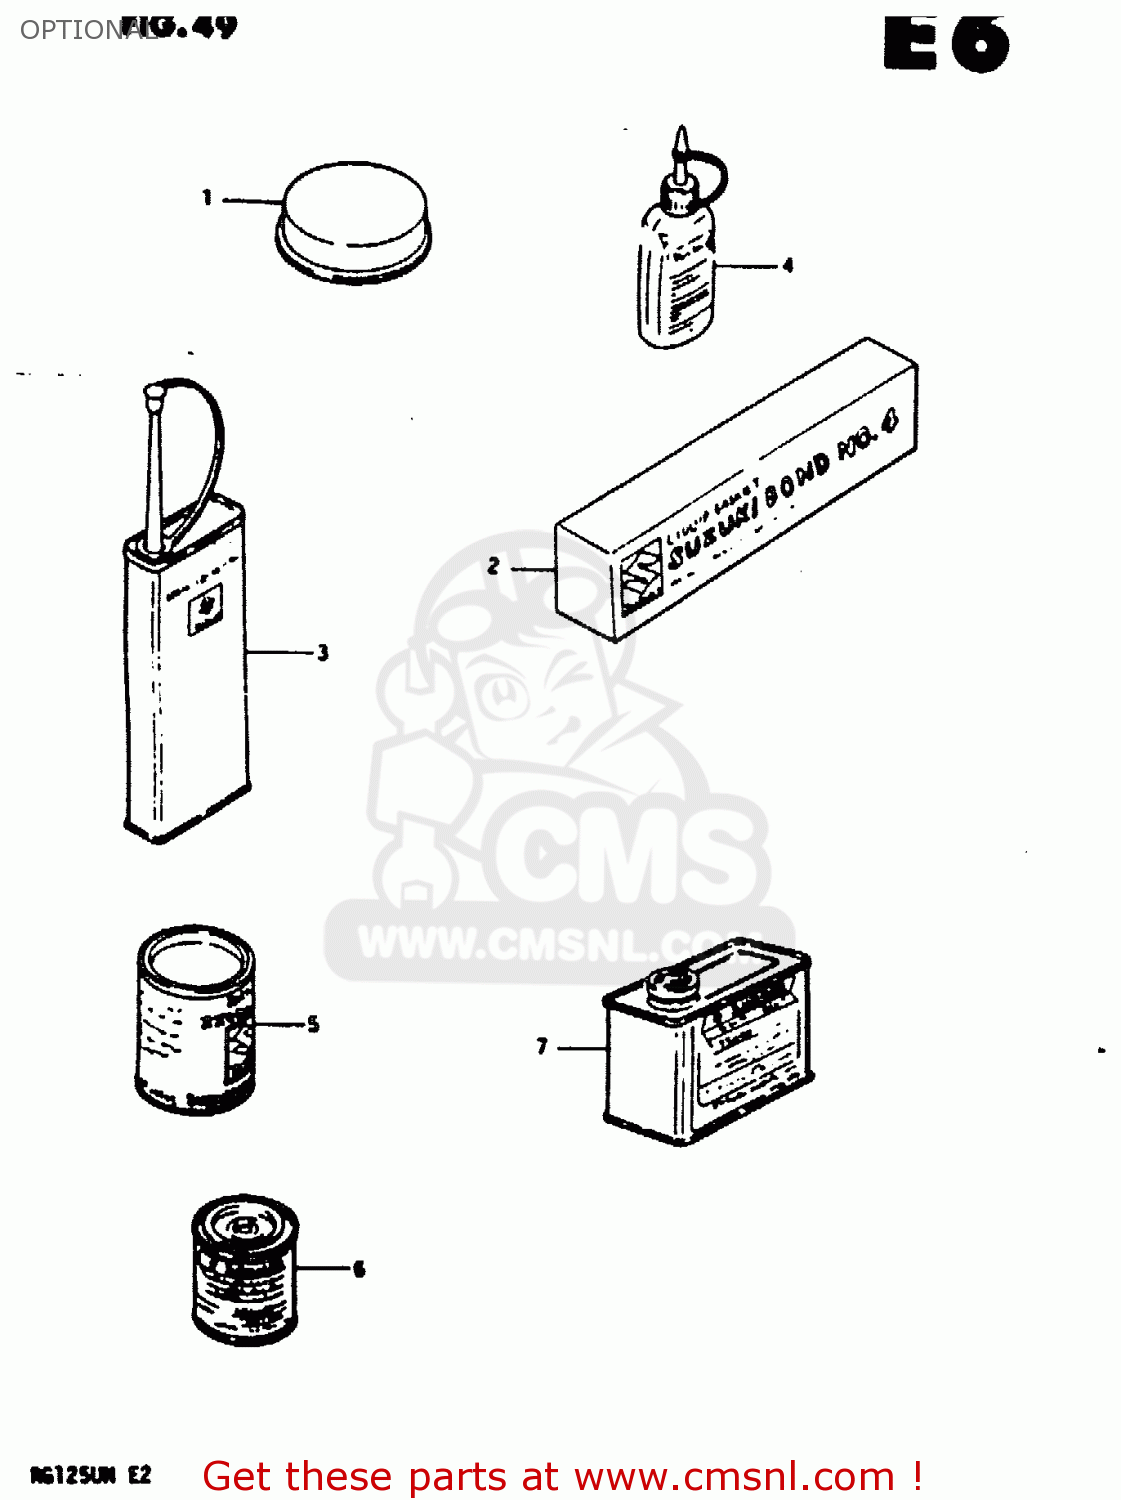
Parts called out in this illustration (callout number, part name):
1	GREASE,PBC FOR BRK PAD 20G
2	BOND 1104
3	THREAD LOCK NO.1401 CLEAR 200G
4	THREAD LOCK NO
5	GREASE(C)EP2 LITHIUM 150G
6	PAINT,BLACK
7	PAINT (BLACK)
